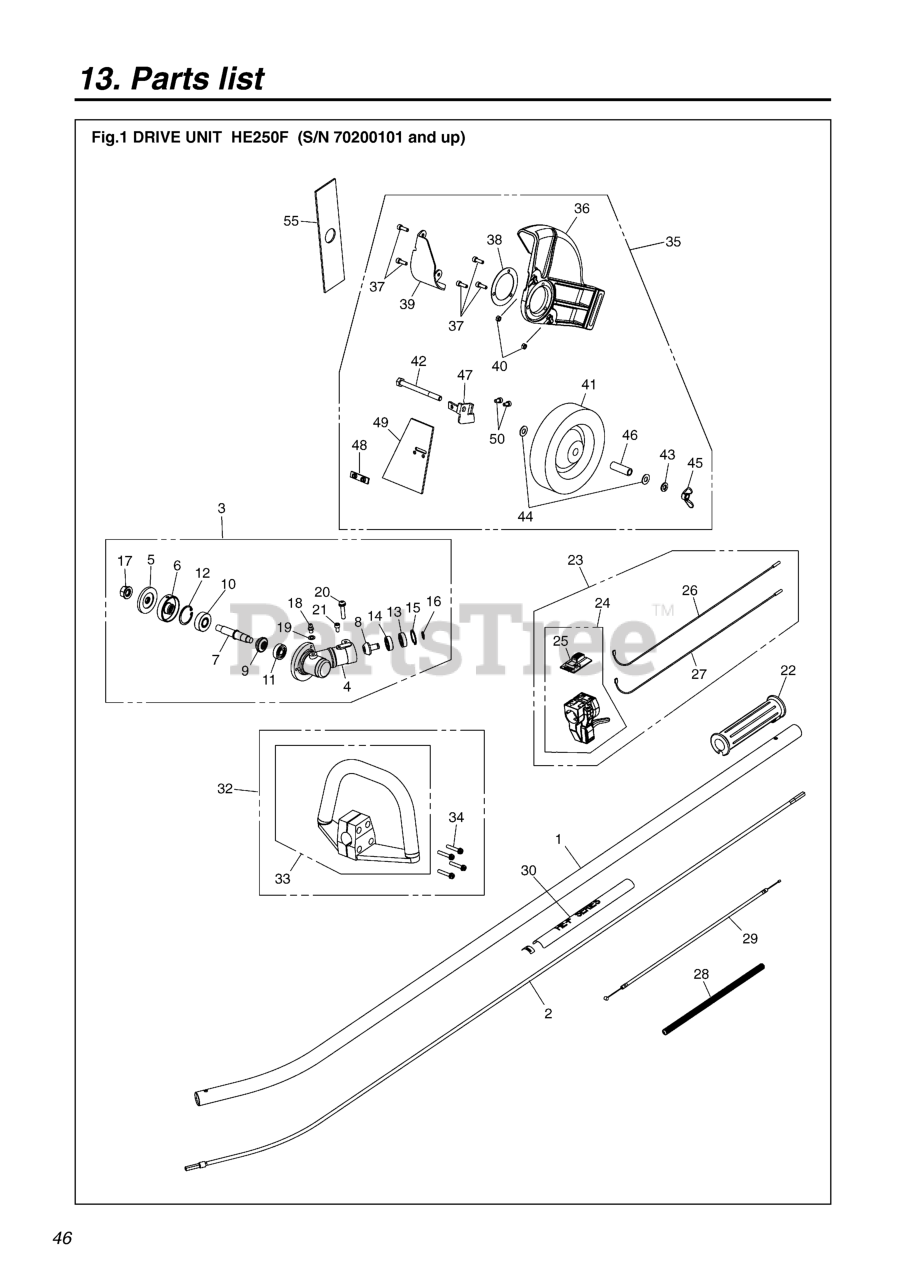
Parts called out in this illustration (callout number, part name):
1	PIPE COMP.
2	SHAFT COMP
4	GEARCASE
5	HOLDER B
6	HOLDER A
8	PINION
9	GEAR
10	BEARING
11	BEARING
12	RING, SNAP, M32 x 1.2
13	BEARING (RPLS T3300-13531)
14	BEARING (RPLS T3403-13530)
15	RING, SNAP, M24 x 1.2
17	NUT
18	FITTING, GREASE
19	WASHER, M6 X .8
20	BOLT
21	BOLT, M5 X 10
22	GRIP
23	LEVER ASSY
24	LEVER
25	COVER COMP. (RP. 6110-14410-02)
26	CORD (A), BLACK
27	CORD (B), RED
28	TUBE (RPLS 4900-72141)
29	CABLE (RPLS 5580-83100)
30	NAMEPLATE
32	HANDLE ASSY. (REPLACES -14001)
33	HANDLE T
34	SCREW
35	GUARD ASSY.
36	GUARD
37	BOLT (M5x0.8-16)
38	PLATE
39	PROTECTOR
40	NUT, M5 X 4
41	WHEEL
42	BOLT
43	WASHER, SPRING
44	WASHER, PLANE(USE 01640-20816)
46	SLEEVE
47	BRACKET
49	RUBBER (FLAP)
50	BOLT, M5 X 10
55	BLADE, EDGER (RPLS 147315)
